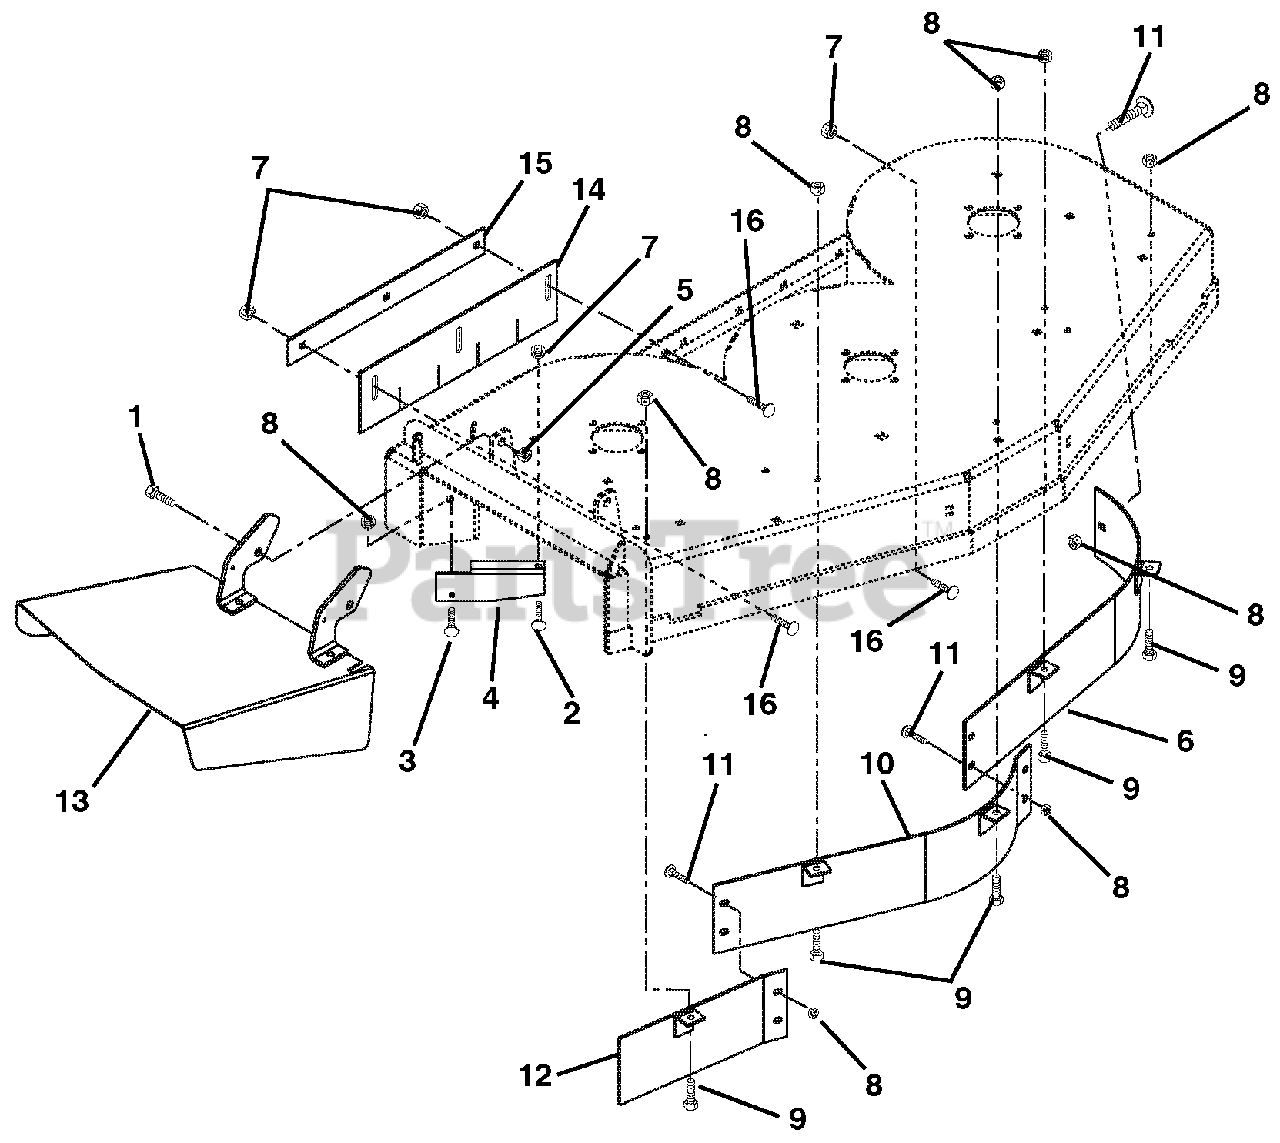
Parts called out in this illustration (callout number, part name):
1	Bolt-Hex .50-13 x 1.25 Grade 5
2	Bolt-Round Head Square Neck .38-16 x .75 Grade 5
3	Bolt-Round Head Square Neck .31-18 x 1.00 Grade 5
4	Deflector 48" (106, 107, 108)
5	Nut-Locking-Nylon .50-13
6	Weldment- Upper Baffle Left (106, 107, 108)
7	Nut-Locking-Top-Flange .38-16
8	Nut-Locking-Top-Flange .31-18
9	Bolt-Hex .31-18 x .75 Grade 5
10	Weldment- Upper Baffle Center (106, 107, 108)
11	Bolt-Round Head Square Neck .31-18 x .75 Grade 5
12	Weldment, Right Hand Baffle-Upper (106, 107, 108)
13	Chute-Discharge
14	Skirt- Rubber
15	Strip- Striper Mount
16	Bolt-Round Head Square Neck .38-16 x 1.00 Grade 5
